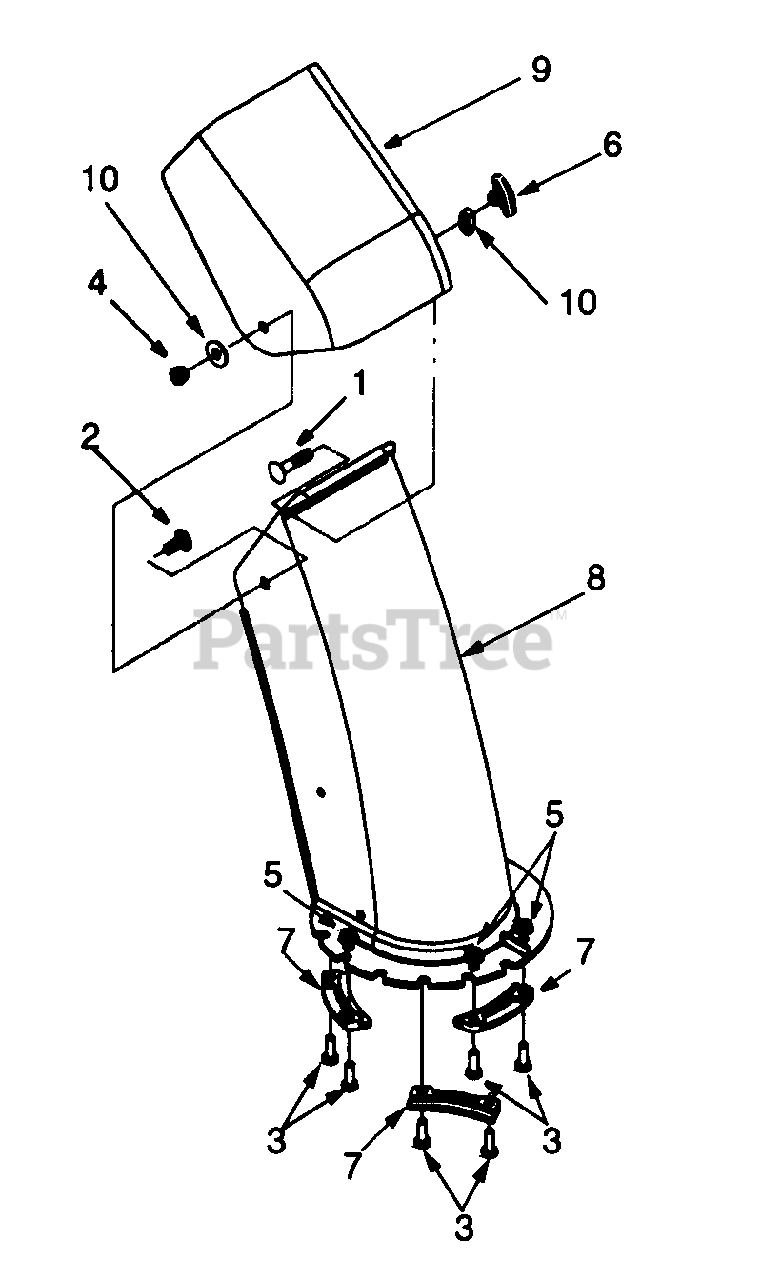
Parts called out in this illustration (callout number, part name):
1	Carriage Screw 5/16-18 x 1.0"
2	Carriage Bolt 5/16-18 x 0.75"
3	Hex Screw 1/4-20 x 0.75"
4	Hex Lock Nut
5	Flanged Lock Nut
6	Knob
7	Chute Flange Keeper
8	Lower Chute
9	Upper Chute
10	Washer
